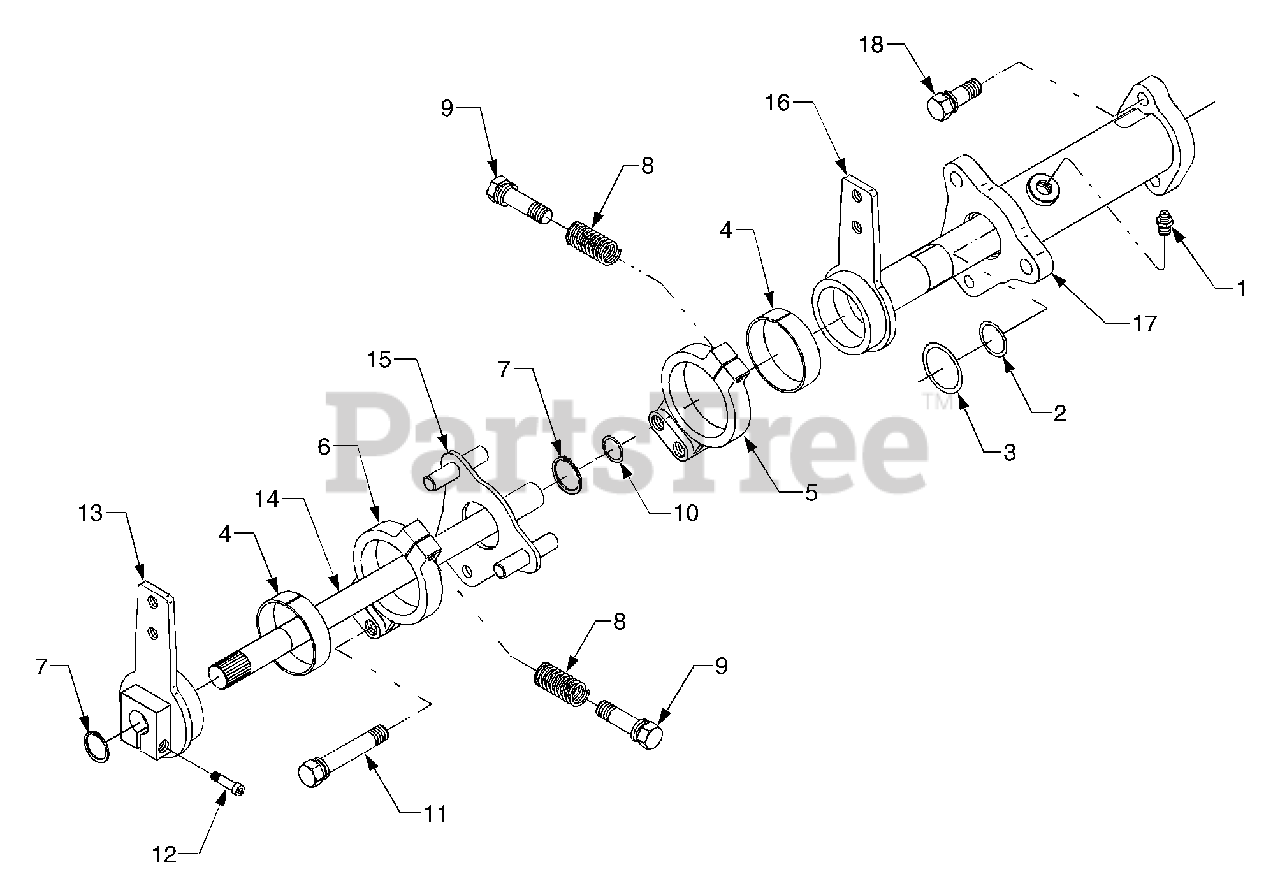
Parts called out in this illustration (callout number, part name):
1	Nipple, Grease
5	Hub, 1 Clutch
6	Hub, 2 Clutch
13	Lever, Control
14	Shaft
17	Support, Hydraulic Lever
